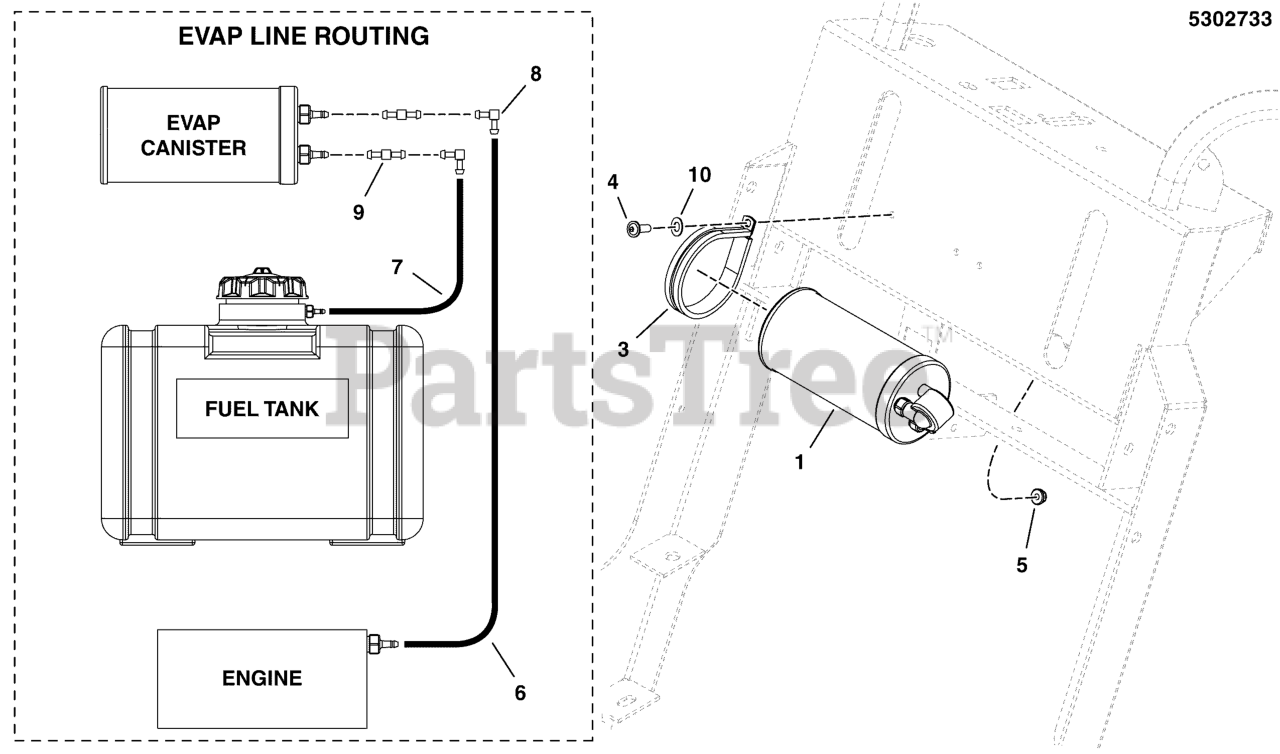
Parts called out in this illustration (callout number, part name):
1	CNSTR, CARB, 6 GAL
2	DECAL, EPA CERT, WALKS
3	CLAMP, 3" ID, CUSHIONED, STAINLESS
4	SCREW, #10-24 X 1 RS, CZ
5	NUT, #10-24 HEX
6	HOSE, VAPOR, 5MM ID, 43.00 LG
7	HOSE, VAPOR, 5MM ID, 16.00 LG
8	FITTING, 90 DEG, 3/16X3/16, SANTOPRENE
9	FITTING, STRAIGHT, 3/16X3/16, PLASTIC
10	WASHER, #10 SAE
